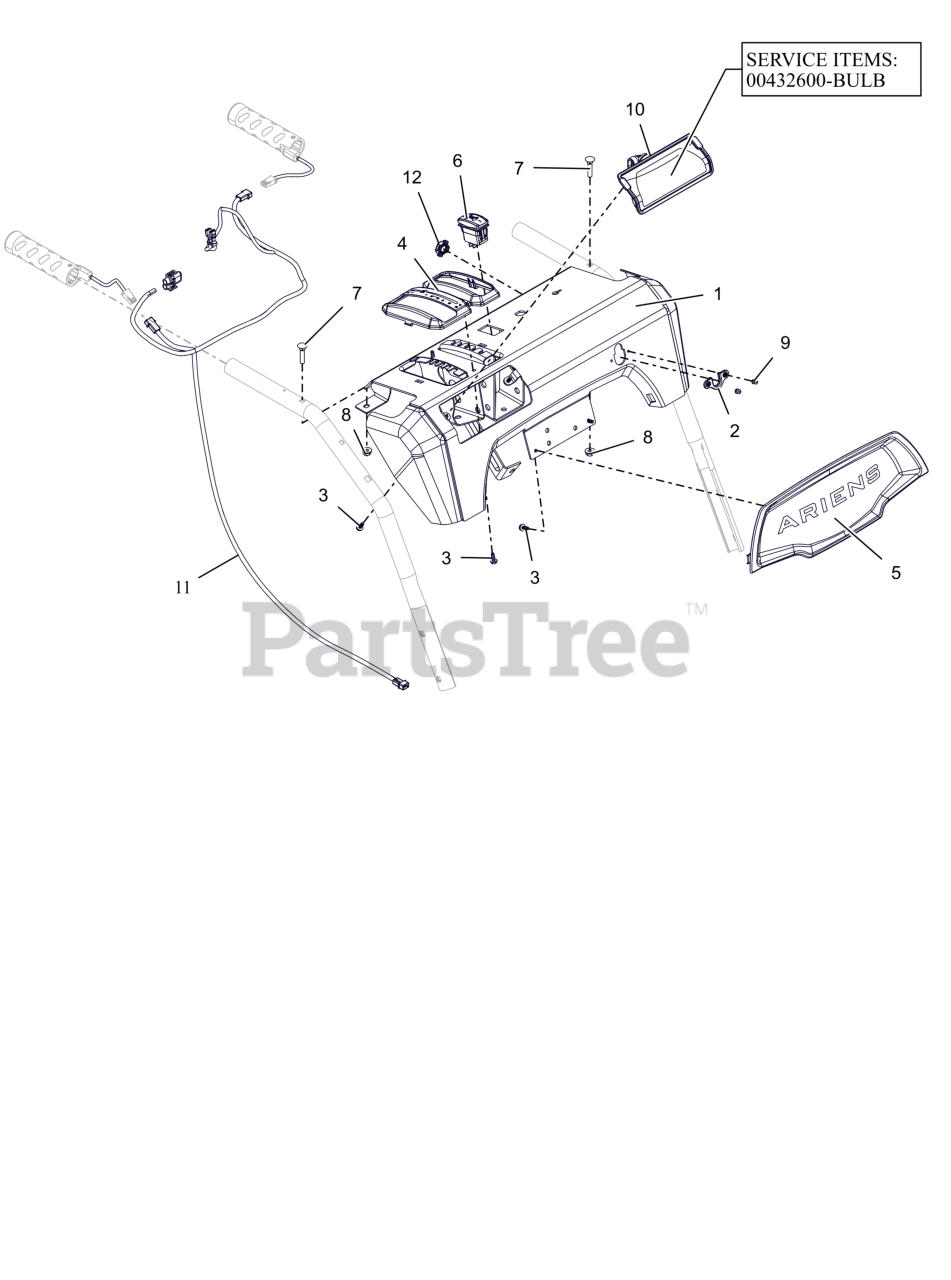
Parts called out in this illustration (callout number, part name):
1	CONTROL PANEL W/DECAL FRIC-ID
2	GROMMET, CABLE, QUICK TURN 2
3	SCR, PLASTIC #10X.50
4	BEZEL, SHIFT - FRICTION SNOW
5	BEZEL, DASH - ARIENS LG DASH
6	SWITCH,ROCKER SPST-ON/OFF
7	BLT-RDHDXLSQNK.25-20X1.25 G5ZC
8	NUT-LK-CTR-FLG .25-20 ZC120
9	RVT-POP #43 .125X.313 STL ZINC
10	HEADLIGHT ASY, HALO 20W 2SHOT
11	HARNESS, LIGHT & WARMER
12	CRANK BUSHING, NYLON CHUTE BK
